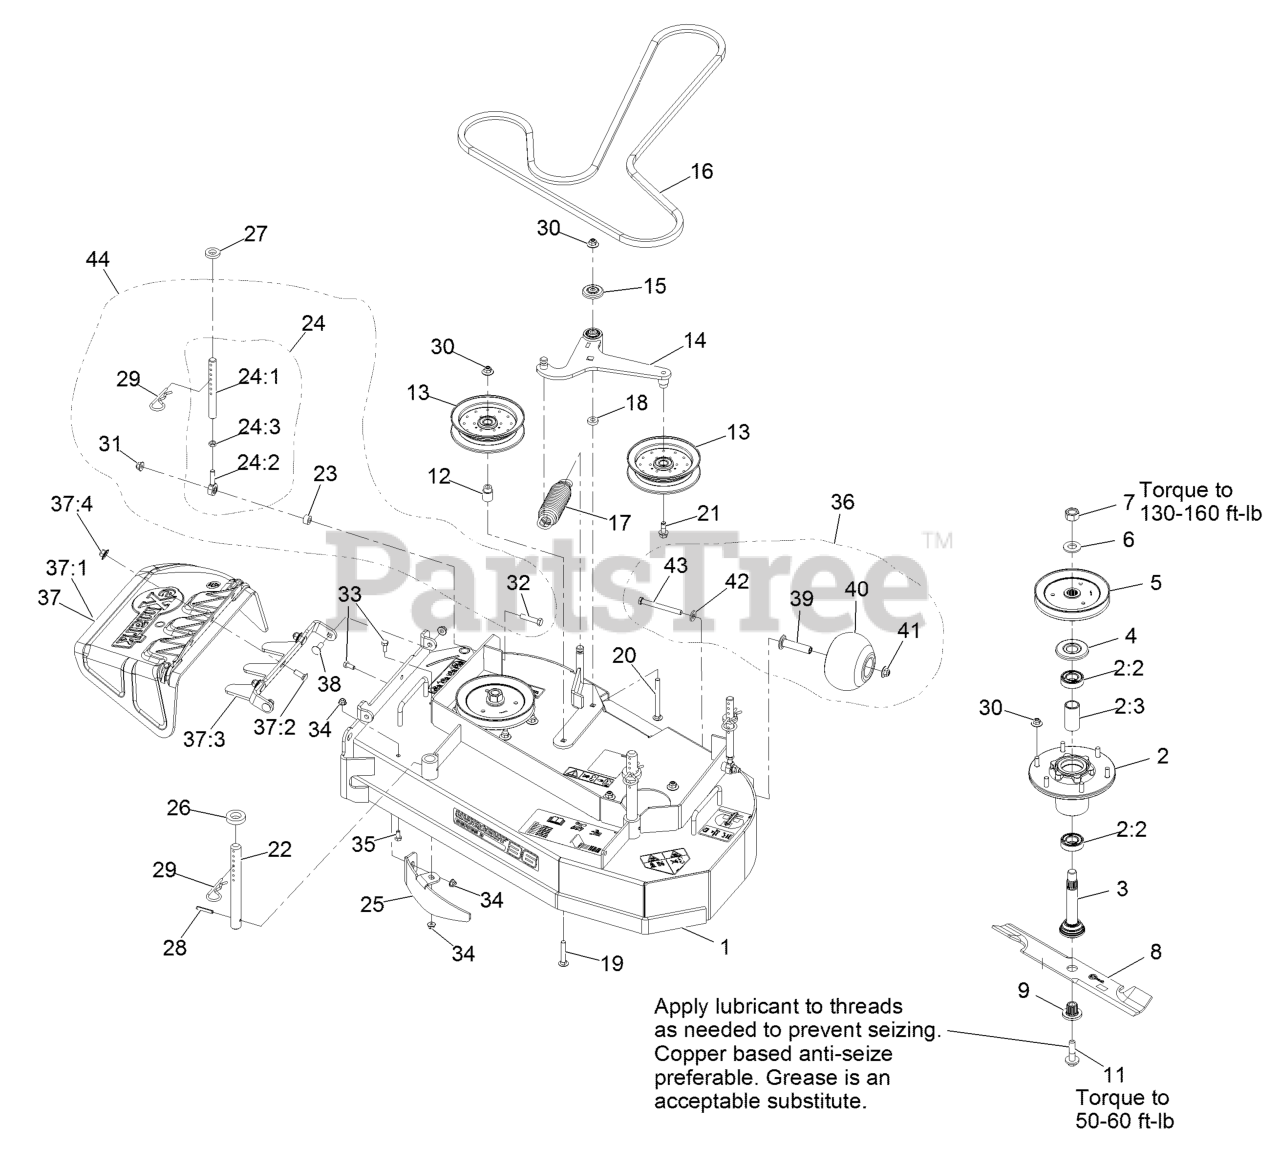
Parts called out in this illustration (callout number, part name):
1	ASM, DECK W/ DECALS, 36"
2	ASM-CUTTER HSG WITH BEARINGS
2:2	BEARING-BALL
2:3	SPACER-BEARING
3	ASM-SPINDLE AND SEAL
4	GUARD,BEARING TOP .989
5	SHEAVE,BLADE DRIVE 6.50
7	NUT-HEX
9	BUSHING,SPLINED
11	SCREW,SEMS 1/2-20 X 2.19
12	BUSHING-IDLER
14	ASM-ARM, IDLER
15	GUARD-TOP
16	BELT-5V
17	SPRING-EXTENSION
18	SPACER
19	Bolt-Carriage 3/8-16 X 2 1/4
20	SCREW-CARR
21	SCREW-HFH
22	ROD,DECK SUPPORT
24:1	LINK,SUPPORT
24:2	BALLJOINT
24:3	NUT-HJ
25	BAFFLE, DOGLEG
26	SPACER-DECK SUPPORT
29	PIN,HAIR COTTER
30	Nut-Nyloc 3/8-16 Flg
31	NUT-HF, NI
32	SCREW-HH
33	SCREW-HH
34	NUT-HF, NI
35	SCREW-HH
36	KIT, ANTI-SCALP ROLLER
37	ASM, DISCHARGE CHUTE
37:1	CHUTE,DISCHARGE
37:2	BRACKET, DISCHARGE CHUTE
37:3	SCREW-CARR
37:4	Nut-Nyloc 3/8-16 Flg
38	SCREW-CARR
39	AXLE, ROLLER
40	ROLLER-SCALP, ANTI
41	Nut-Nyloc 3/8-16 Flg
42	WASHER-BELLEVILLE
43	SCREW-HH 3/8-16 X 3 3/4 GR 8
44	KIT,SUPPORT LINK W/PIN
